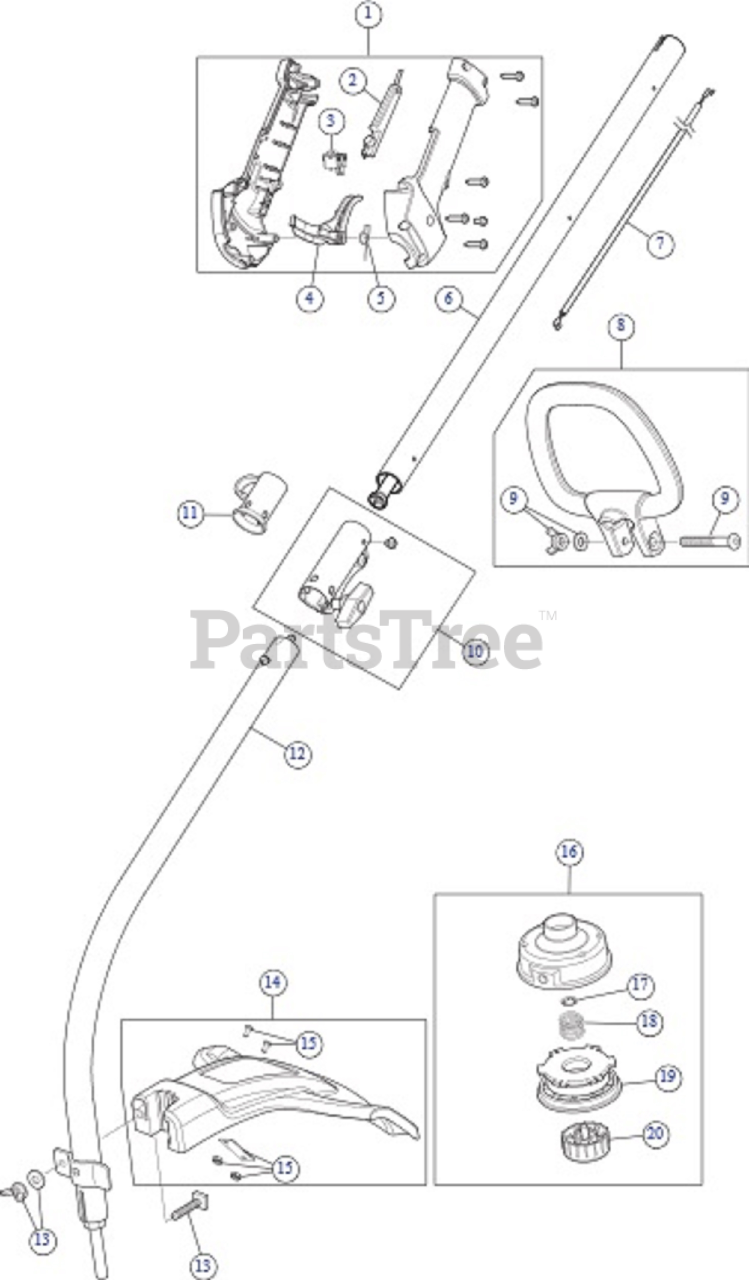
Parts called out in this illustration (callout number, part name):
1	Throttle Housing Assembly (Incl. 2 - 5)
2	Throttle Trigger Lock-Out
3	Trigger Switch Assembly
4	Throttle Trigger
5	Throttle Trigger Spring
6	Upper Shaft Housing Assembly
7	Throttle Cable
8	D-Handle (Incl. 9)
9	D-Handle Hardware Assembly
10	Split Boom Coupler
12	Lower Shaft Housing Assembly
13	Shield Mounting Hardware
14	Shield Assembly (Incl. 15)
15	Blade Assembly
16	Outer Spool Assembly (Incl. 17)
19	Inner Reel
20	Bump Head Knob Assembly
